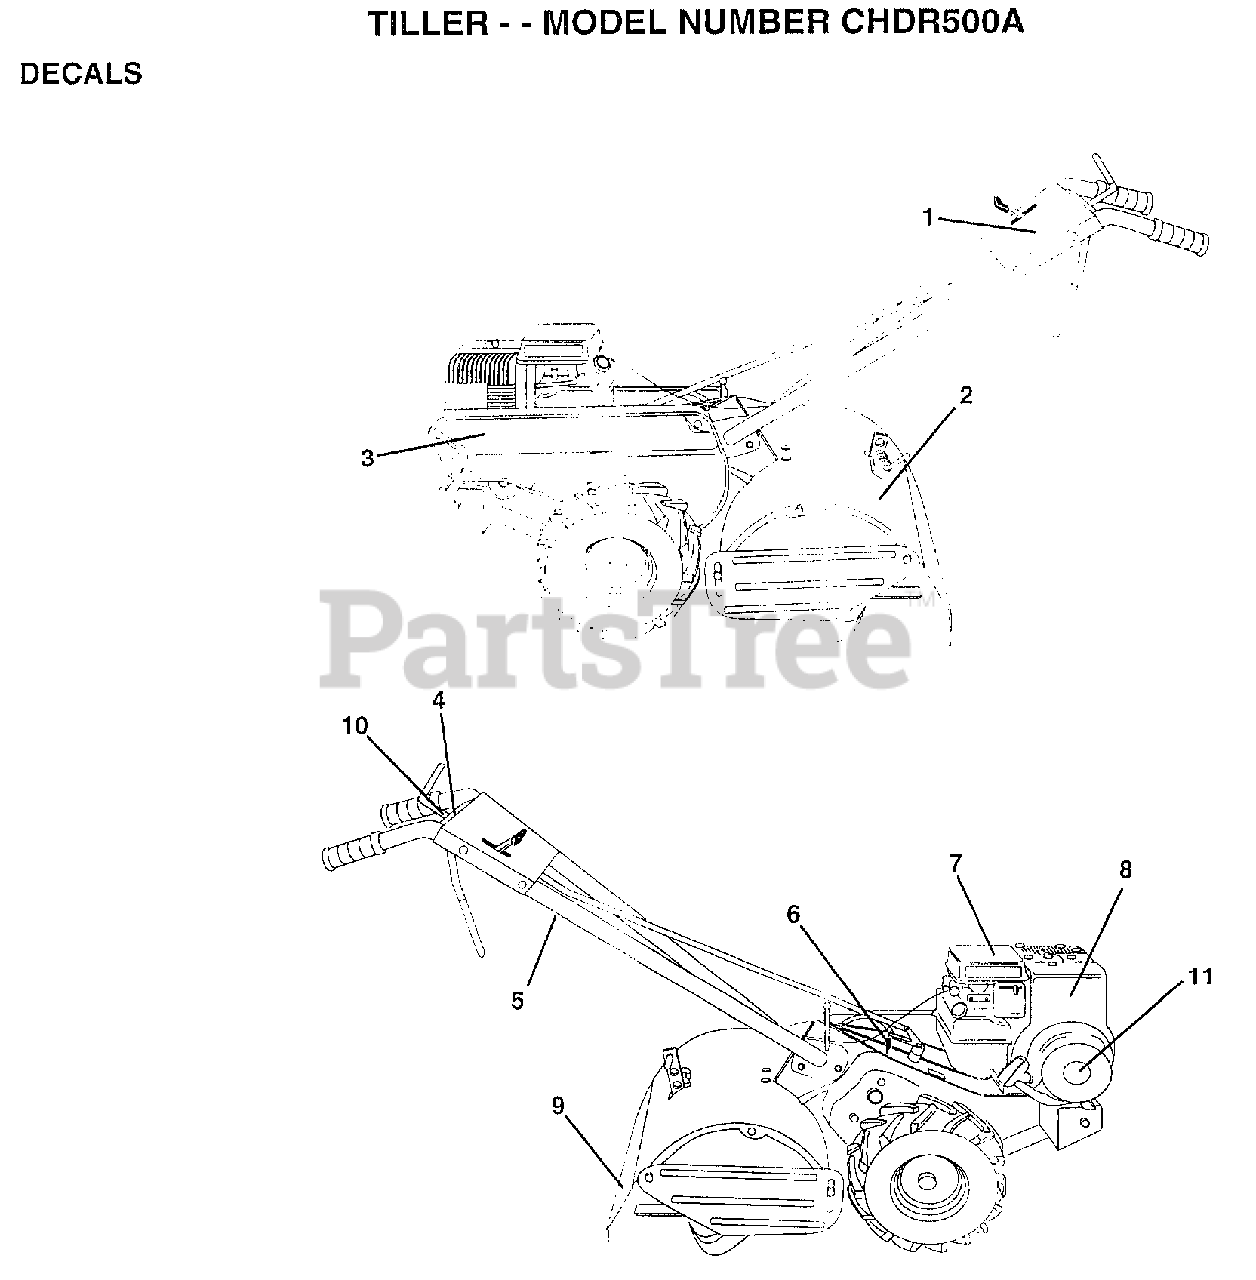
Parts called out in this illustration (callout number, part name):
1	"DECAL PANEL,CTRL"
2	"DECAL SHIELD,TINE"
3	"DECAL GUARD, BELT"
5	DECAL.HAND.PLACE
6	DECAL TI
7	DECAL TI
8	DECAL, BRIGGS & STRATTON
10	DECAL REVERSE
11	DECAL, 5 HP
